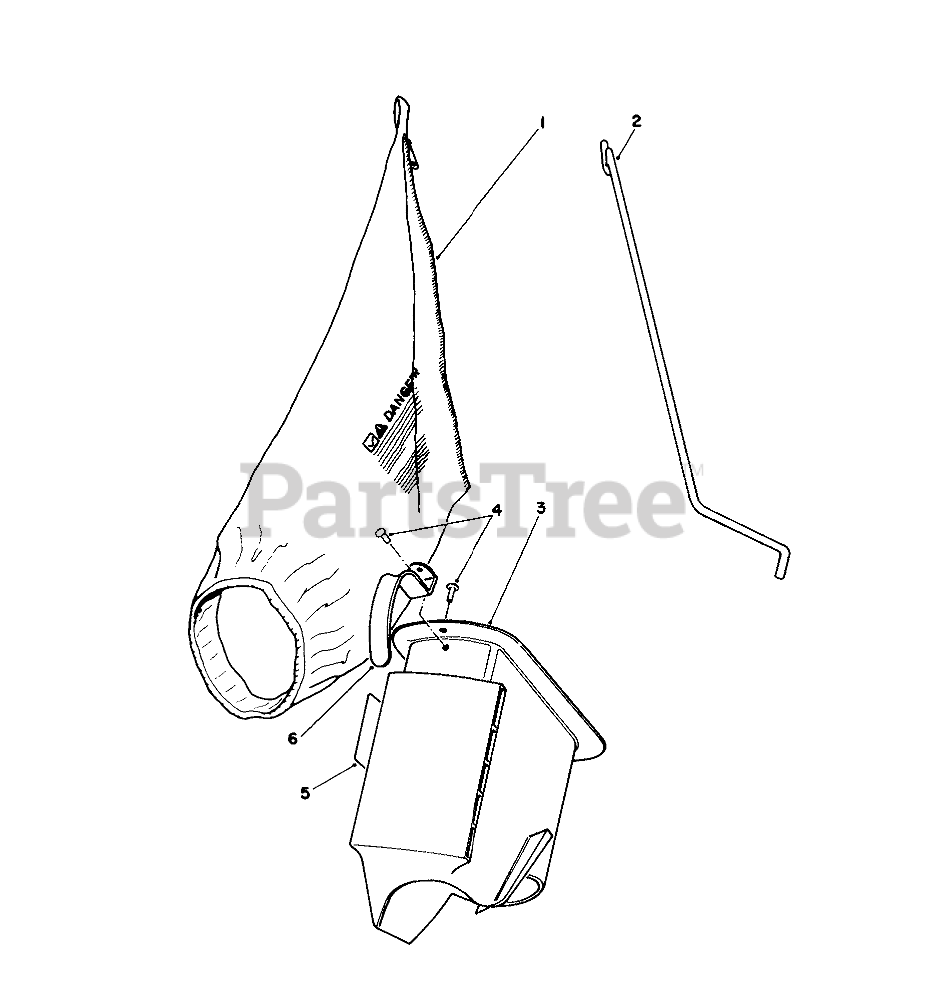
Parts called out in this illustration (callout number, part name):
1	BAG REPLACMNT44-0540
2	BAG ROD
3	Grass Chute (Incl. Ref. #4 & 6)
4	RIVET 3/16 X 7/16
5	BAG CHUTE DECAL
6	HANDLE-GRASS CHUTE
